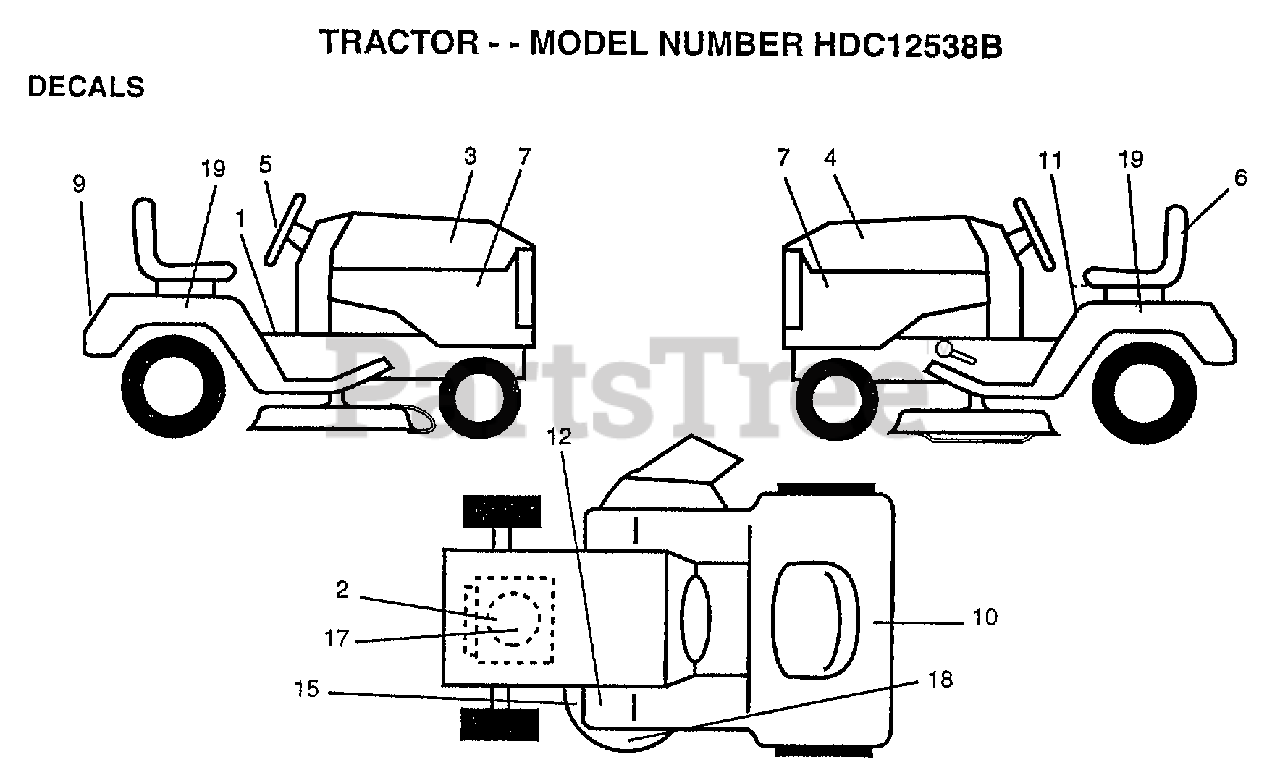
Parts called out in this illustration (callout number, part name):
2	DECAL, HP ENGINE
3	"DECAL HOOD,RH"
4	DECAL HOOD LH
5	"DECAL INS,STRG WH"
6	"DECAL SEAT,REPLCM"
7	"DECAL PENL,SIDE"
9	DECAL-FENDER
10	DECAL.BATRY.3-3908
11	"DECAL FENDER,DANG"
12	DECAL CLUT/BRAKE
15	DECAL
17	"DECAL ENGINE,REPL"
18	"DECAL MOWER,HOME"
19	"DECAL FENDER,5 SP"
